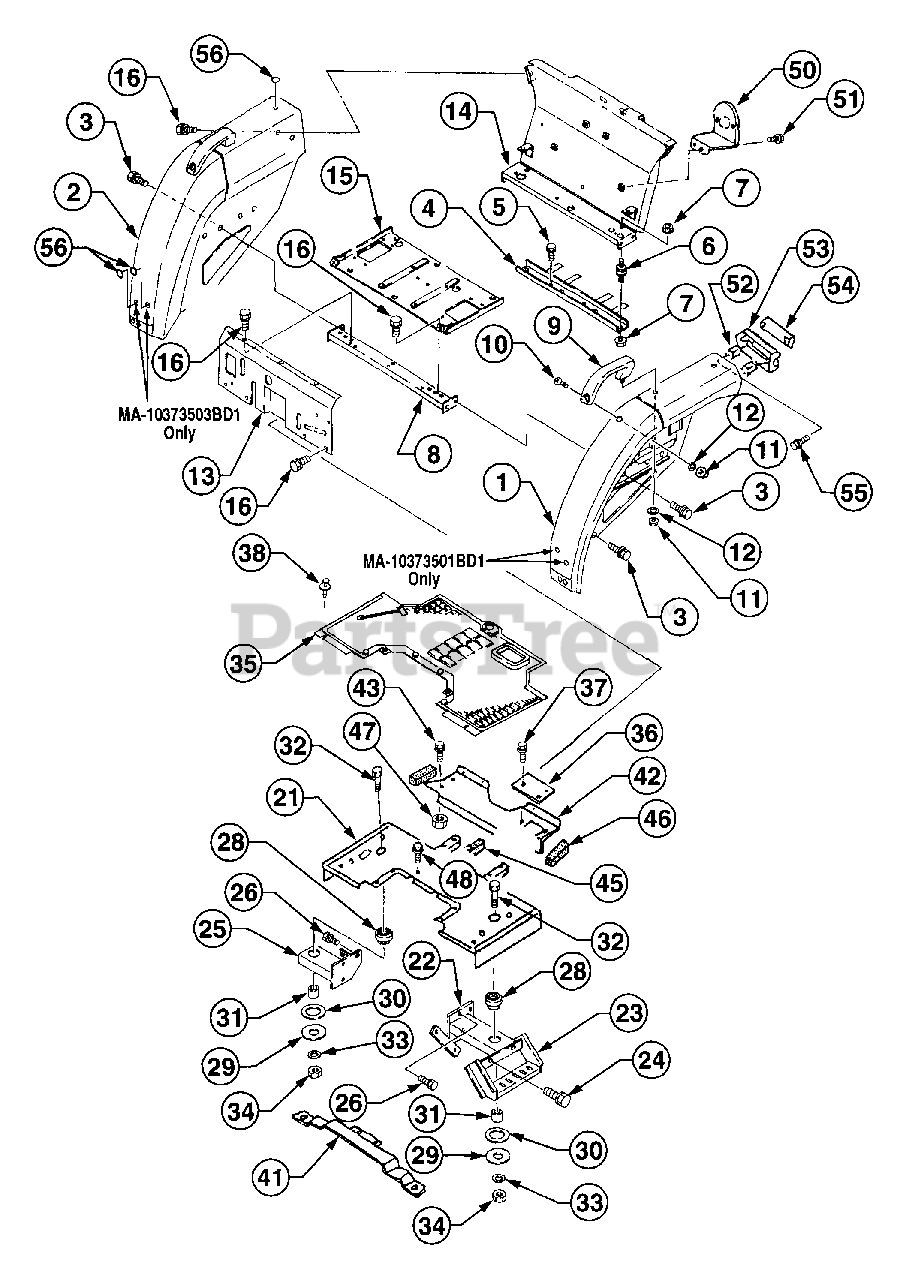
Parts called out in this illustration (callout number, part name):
8	Support, Fender
14	Cover, Center
22	Bracket L.H.,Step
25	Bracket R.H.,Step
45	Cushion, Rubber
46	Cushion, Rubber
50	Bracket, Tail Lamp
56	Mark, y
